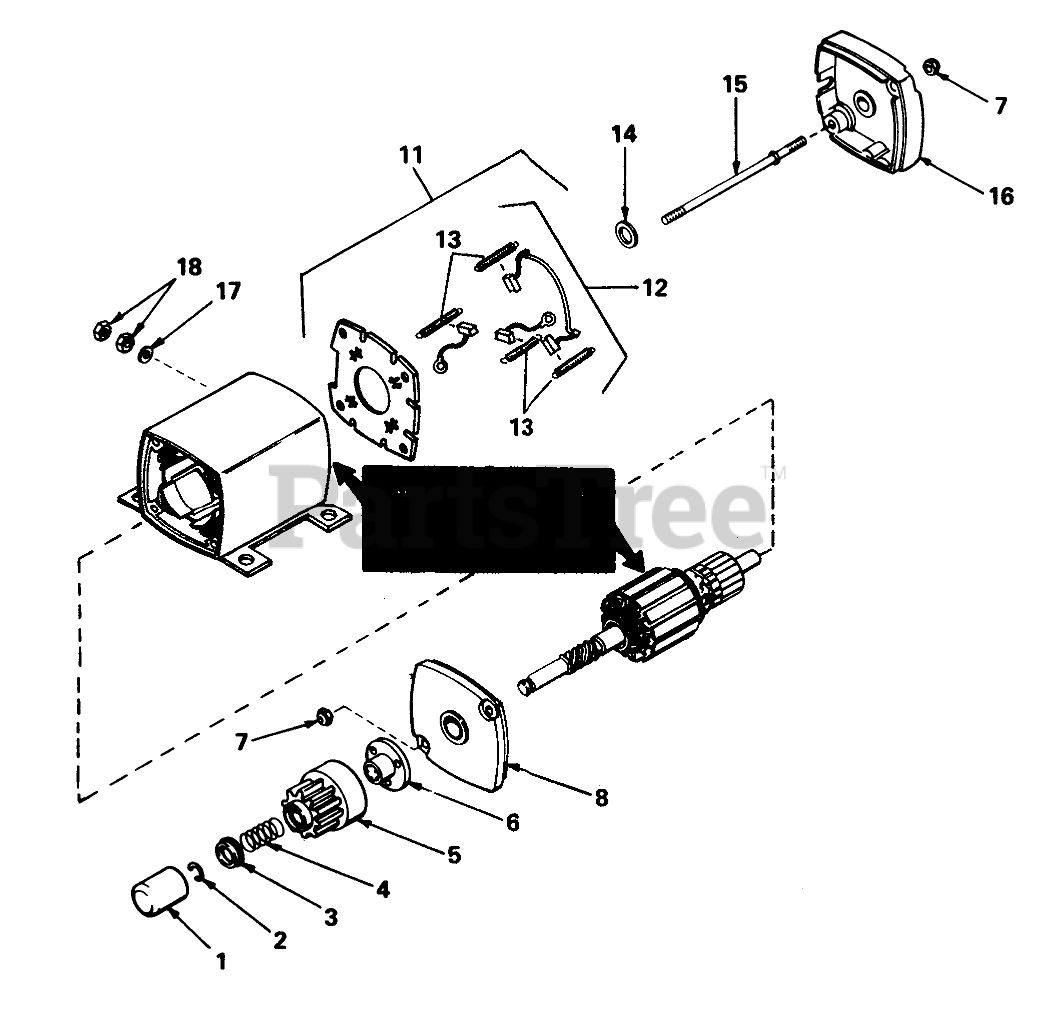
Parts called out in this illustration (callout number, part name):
1	Cover-Dust
2	Ring-Retainer
3	Retainer-Spring
4	Spring-Anti Drift
6	Nut-Engaging
7	Nut-Lock
8	Cap Assy., Drive End
11	Card Assv Brush (Incl. No.12)
12	Brush & Spring Kit (Incl. 4 pcs. of No.13)
13	1545D SUP TO W/3256
14	Washer-Thrust
16	2035A67 WIZARD W/34
18	Nut-Hex
